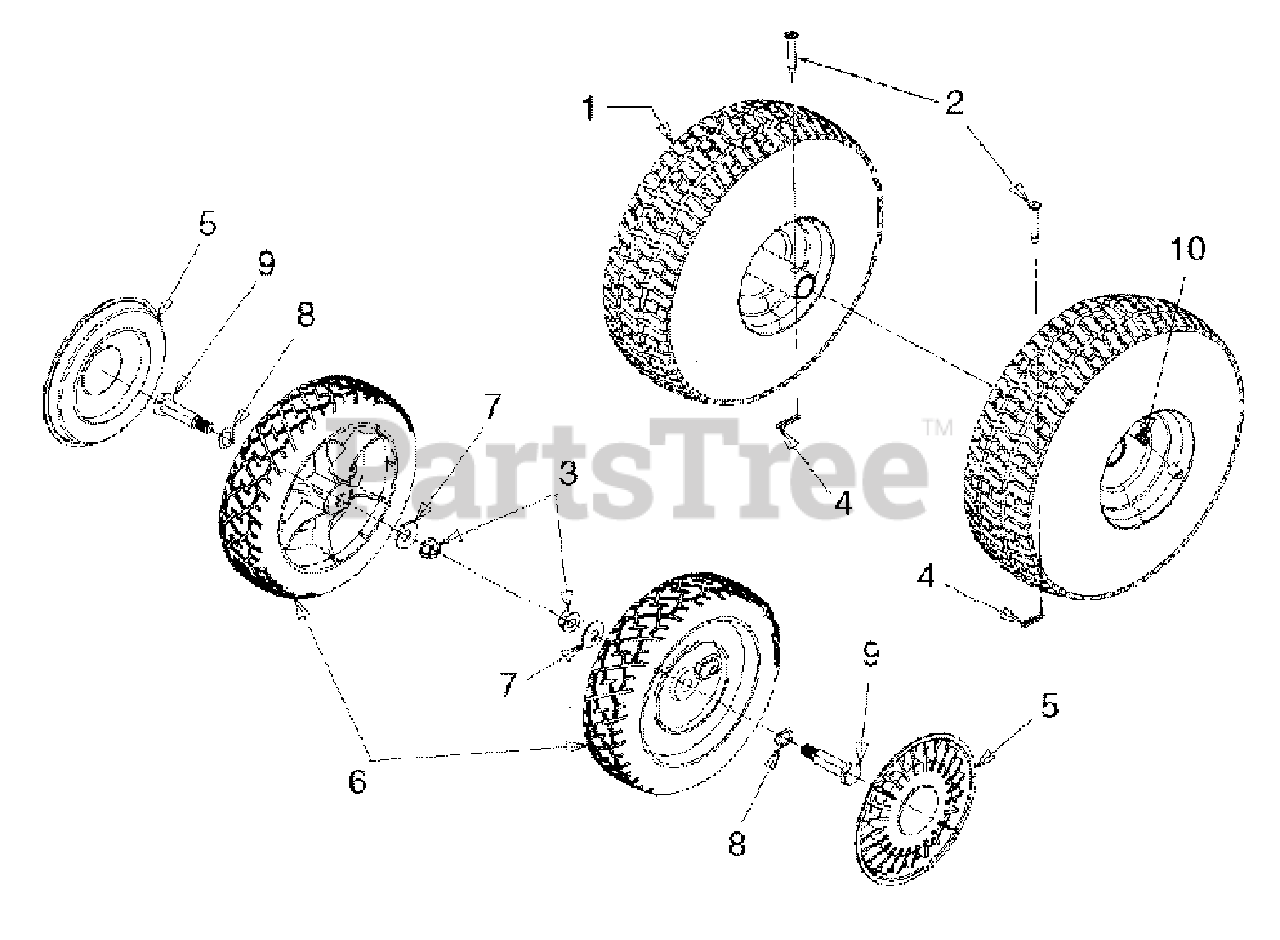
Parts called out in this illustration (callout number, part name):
1	Wheel Ass'y Complete
1	Rim Assembly
1	Tire, Pneumatic, 10 x 4
2	Pin, Clevis, .25 x 1.53
3	Nut, Hex Flange Lock, 3/8-16
4	Pin, Internal Cotter
5	Hubcap, Grey
6	Wheel Ass'y Complete, 8 x 2.0
7	Washer, Bell, .401 x .870 x .06
8	Washer, Wave, .53 x .78 x .013
9	Shoulder Bolt
10	Valve, Tubeless Air
